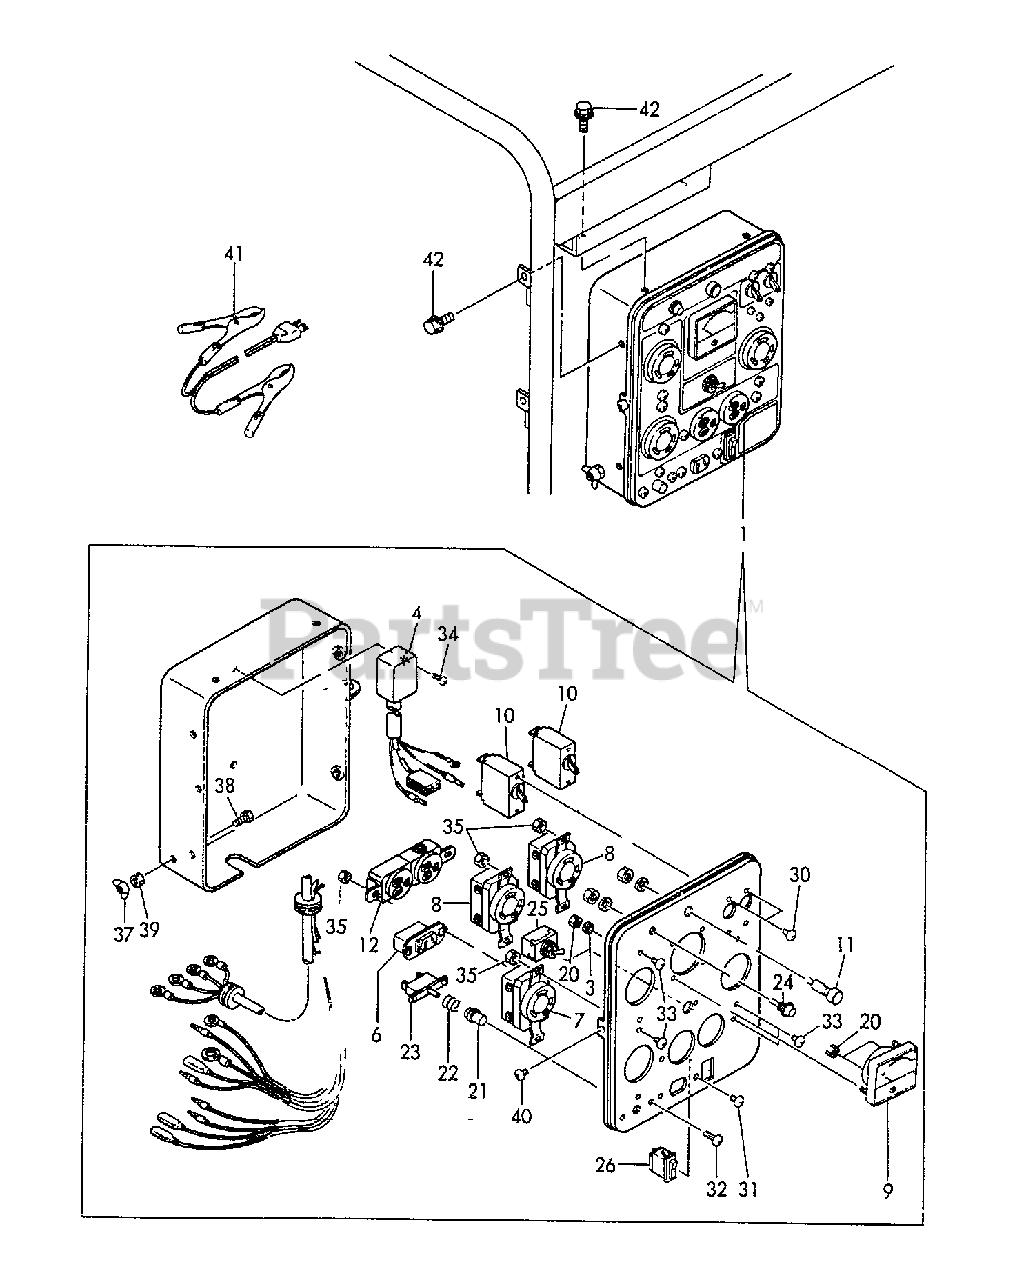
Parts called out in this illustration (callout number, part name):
1	PANEL BOX ASSY
3	LOCKWASHER
4	SENSOR, OIL
6	DC CONNECT
7	CONNECTOR
8	CONNECTOR
9	METER, VOLTAGE - 300V
10	AC BREAKER
11	LAMP, PILOT
12	AC CONNECT
20	NUT - 3
21	CAP, BREAKER
22	SPRING, BREAKER
23	BREAKER
24	LAMP, OIL ALERT
25	SWITCH
26	SWITCH
30	SCREW - 3X6
31	SCREW - 3X6
32	SCREW - 3X14
33	SCREW - 4X6
34	SCREW - 5X10
35	NUT - 4
37	WINGNUT - 6
38	BOLT - 6X16 -- PLATED
39	LOCKNUT - 6 -- PLATED
40	SCREW - 4X6
41	CABLE, CHARGING
42	BOLT - 6X8 -- PLATED
